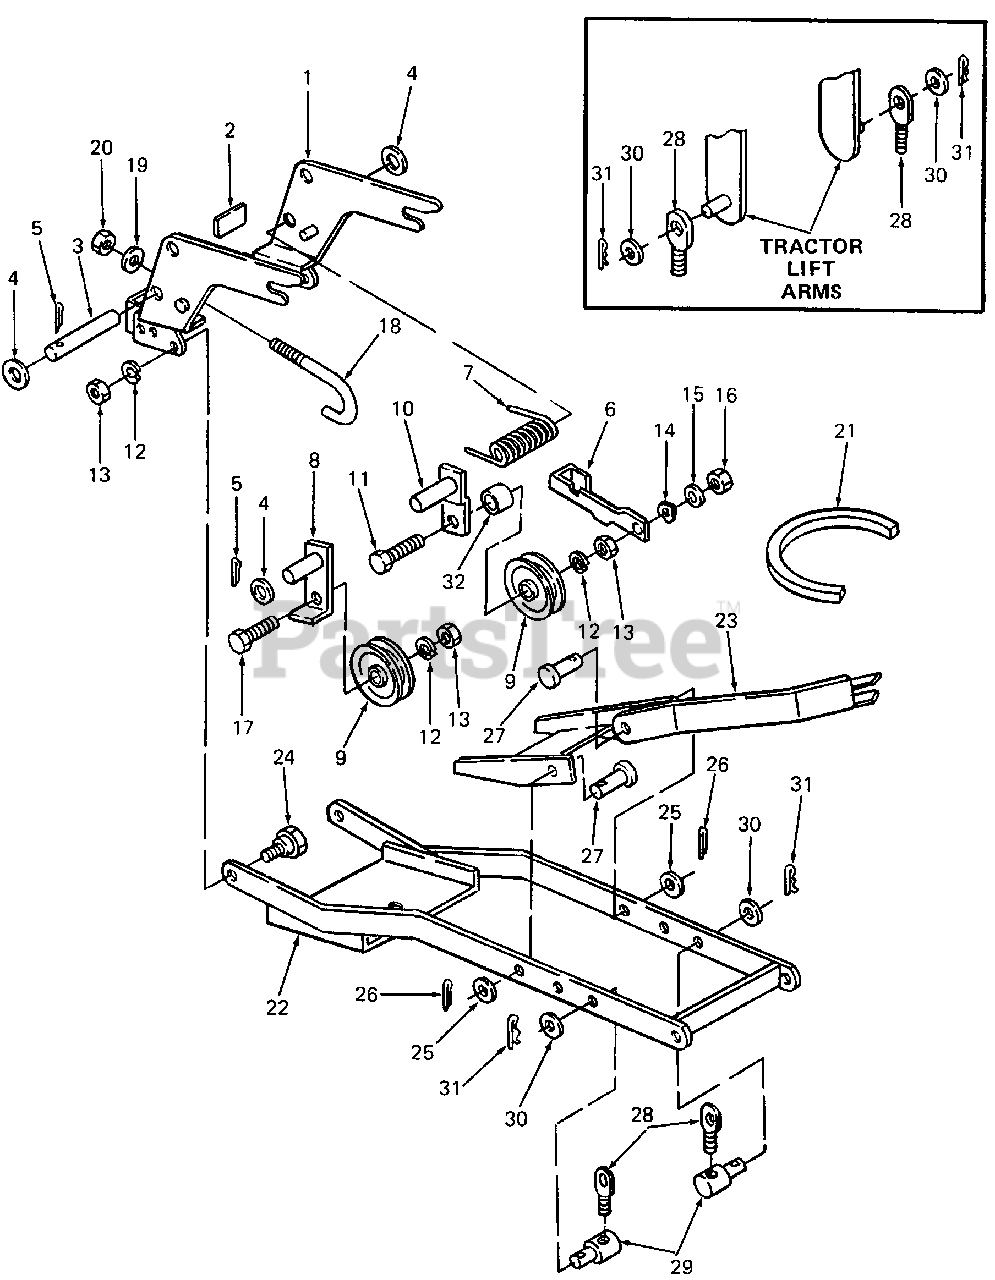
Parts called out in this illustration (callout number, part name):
1	Hanger Assy, Front
2	Graphic, Idler Adjustment
3	Shaft, Idler Pivot
4	Washer, Flat, .640 X .943 X .050
5	Pin, Cotter, 1/8 Dia X 1.0 Lg
8	Arm Assy, Idler - LH
9	Pulley, Idler
10	Arm Assy, Idler - RH
11	Screw, Hex Cap, 3/8-16 X 2.75 Lg GR5
12	Washer, Lock, 3/8
13	Nut, Hex, 3/8-16 GR5
14	Washer, Wave, .406 X .64 X .015 Thk
15	Washer, Flat, .406 X .75 X .063 Thk
16	Nut, Hex Center Lock, 3/8-16 GR5
17	Screw, Hex Cap, 3/8-16 X 1.5 Lg GR5
18	Bolt, Idler Adjuster
19	Washer, Flat, .34 X .68 X .062 Thk
20	Nut, Hex Center Lock, 5/16-18 GR5
21	V-Belt
24	Bolt, Shoulder
25	Washer, Flat, .531 X 1.0 X .027 Thk
26	Pin, Cotter, 3/16 Dia X 1.0 Lg
27	Pin, Clevis, .50 Dia X 2.0 Lg
28	Link, Adjustable
29	Ferrule, Adjustment
30	Washer, Flat, .510 X 1.0 X .060 Thk
31	Pin, Internal Cotter
32	Spacer, .390 X .625 X .50 Lg
